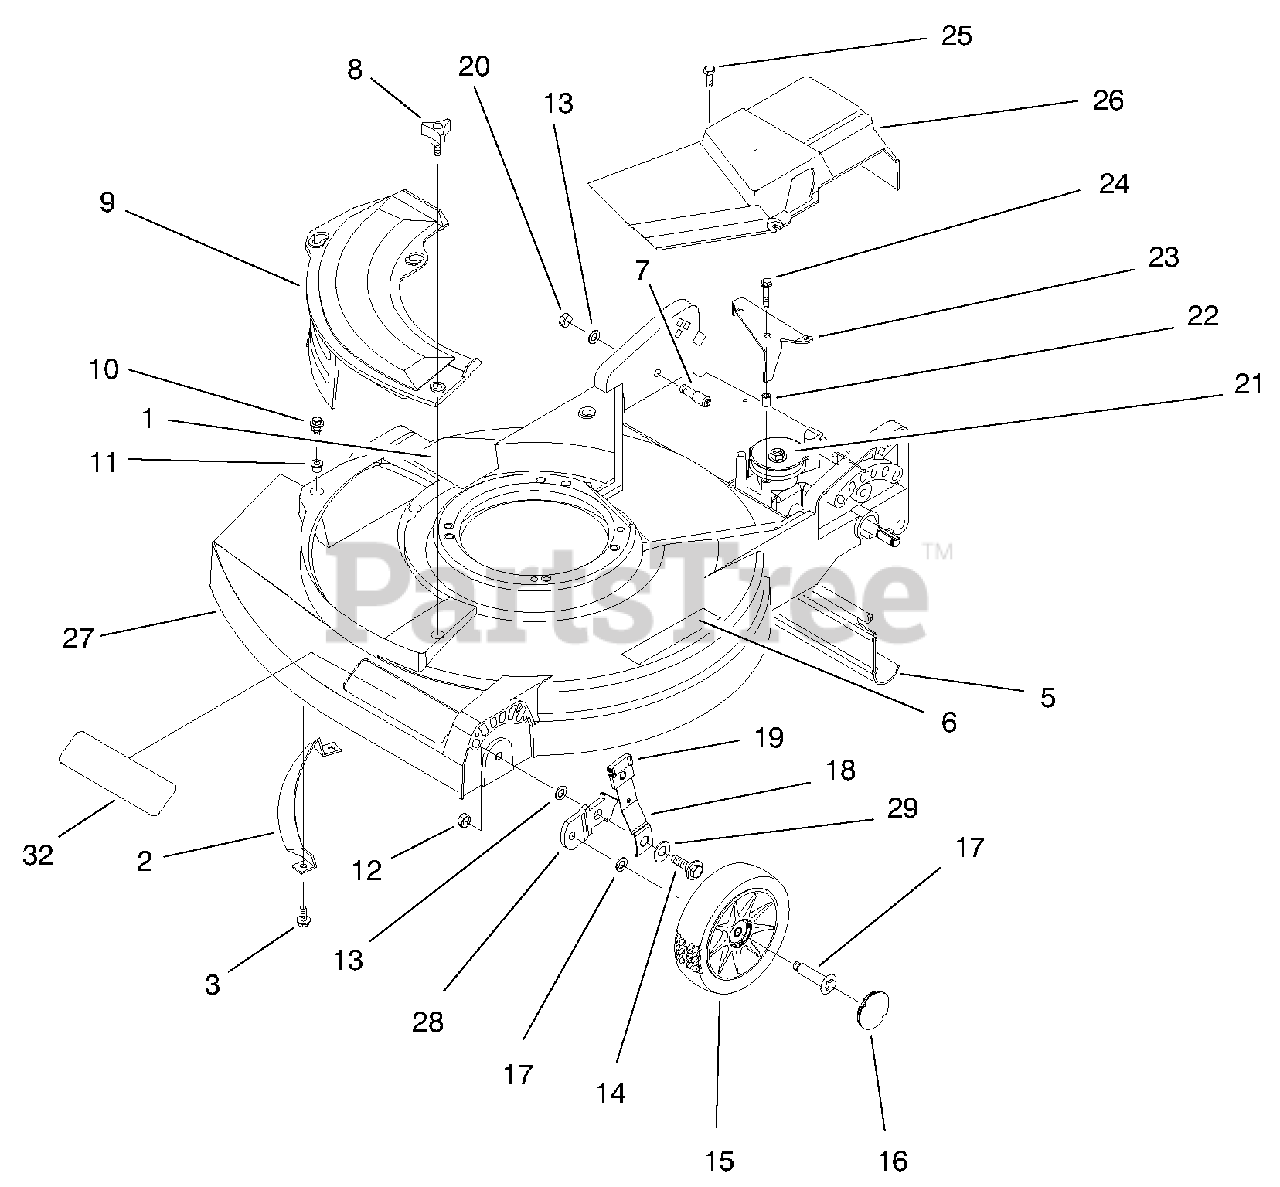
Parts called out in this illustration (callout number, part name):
1	Decal-Danger
2	Toe Bar 21
3	Screw-HWH
5	Shield-Trailing
6	Decal-Warning
7	Bolt-Shoulder
8	Knob-Cover Plate
9	Mulch Plate-21"
10	Screw-Sems
11	Grommet-Plastic
12	Nut-Lock
14	Bolt-Shoulder
15	ASM-Wheel & Tire 6"
17	Bolt-Shoulder 6" Wheel
18	ASM-Spring Arm
19	Knob-Height Adjust
20	Nut-Lock
21	ASM-Gear Case
22	Bushing-Spacer
23	Bracket-Actuator
24	Screw
25	Screw-Thd Form
26	Cover-Drive
27	Housing-21" Sp (Incl. Ref. #1 & 6)
28	Bracket-Wheel Height Adj
29	Washer-Spring
31	Plate-Cover
32	Decal-Deck
